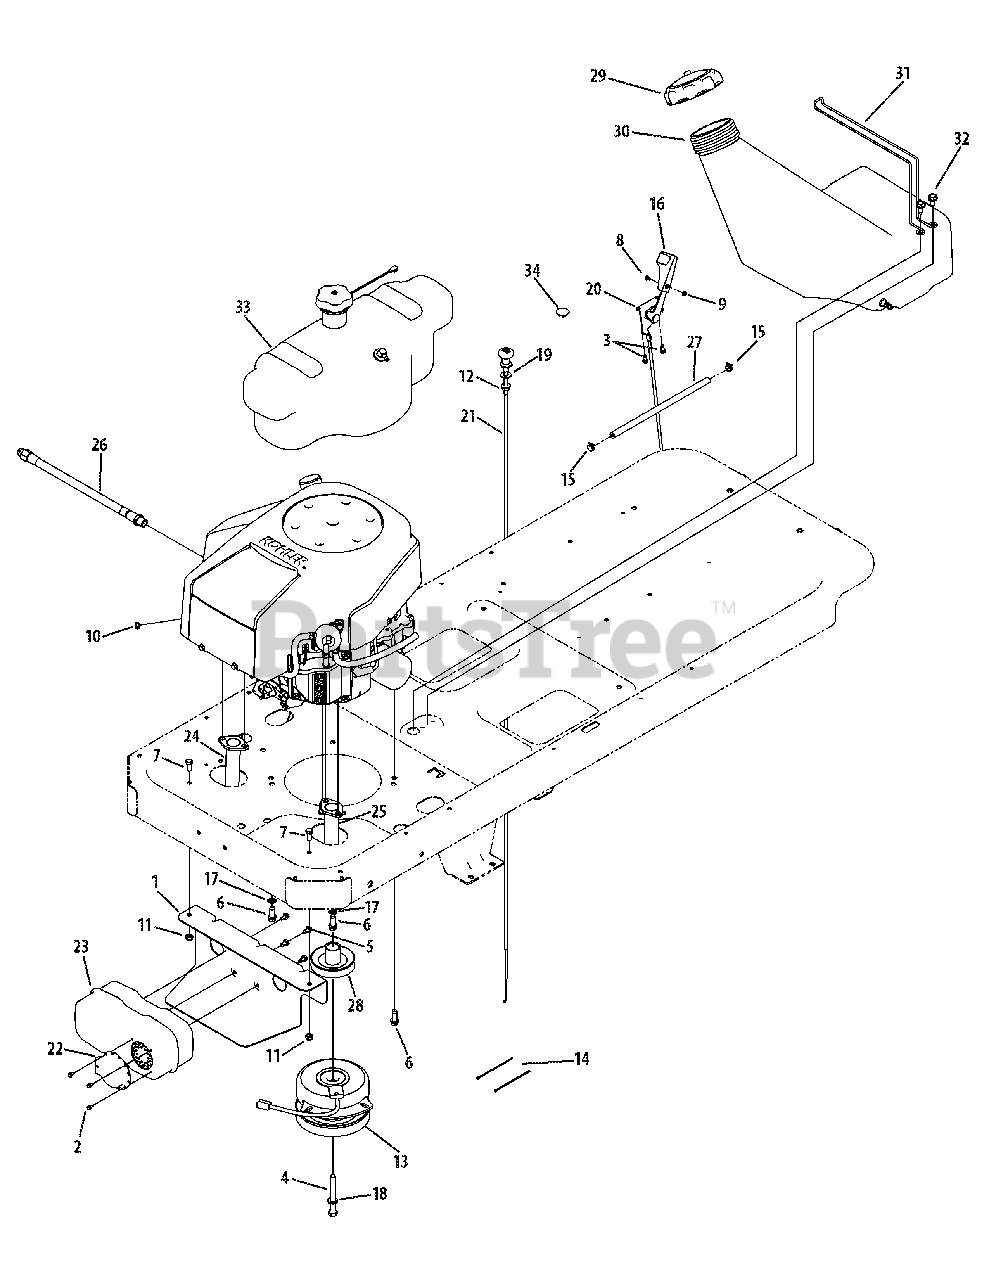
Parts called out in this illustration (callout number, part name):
1	Muffler Mount Bracket
2	Hex Washer Screw, #8-18 x .500
3	Hex Washer Screw, #12-16 x .50
4	Hex Lock Screw, 7/16-20 x 3.50
5	Hex Washer Screw, 1/4-20 x .500
6	Hex Washer Screw, 3/8-16 x 1.000
7	Hex Washer Screw, 5/16-18 x .75
8	Machine Screw, #8-32 x .375
9	Hex Nut, #8-32
10	Sems Nut, 1/4-20
11	Hex Lock Nut, 5/16-18
12	Flange Lock Nut, 3/8-16
13	Electric PTO Clutch
14	Cable Tie
15	Hose Clamp
16	Throttle Control Knob
17	Lock Washer, 3/8
18	Lock Washer, 7/16
19	Flat Washer, .406 x .875 x .059
20	Throttle/Choke Control Cable
21	Choke Cable
22	Muffler Deflector
23	Dual Inlet Muffler
24	Exhaust Pipe, LH
25	Exhaust Pipe, RH
26	Oil Drain Hose
27	Fuel Hose
28	Engine Pulley
29	Fuel Cap
30	Fuel Tank
31	Tank Mounting Wire
32	Hex Washer Screw, 5/16-18 x .750
33	Fuel Tank Assembly
34	Choke Plug
